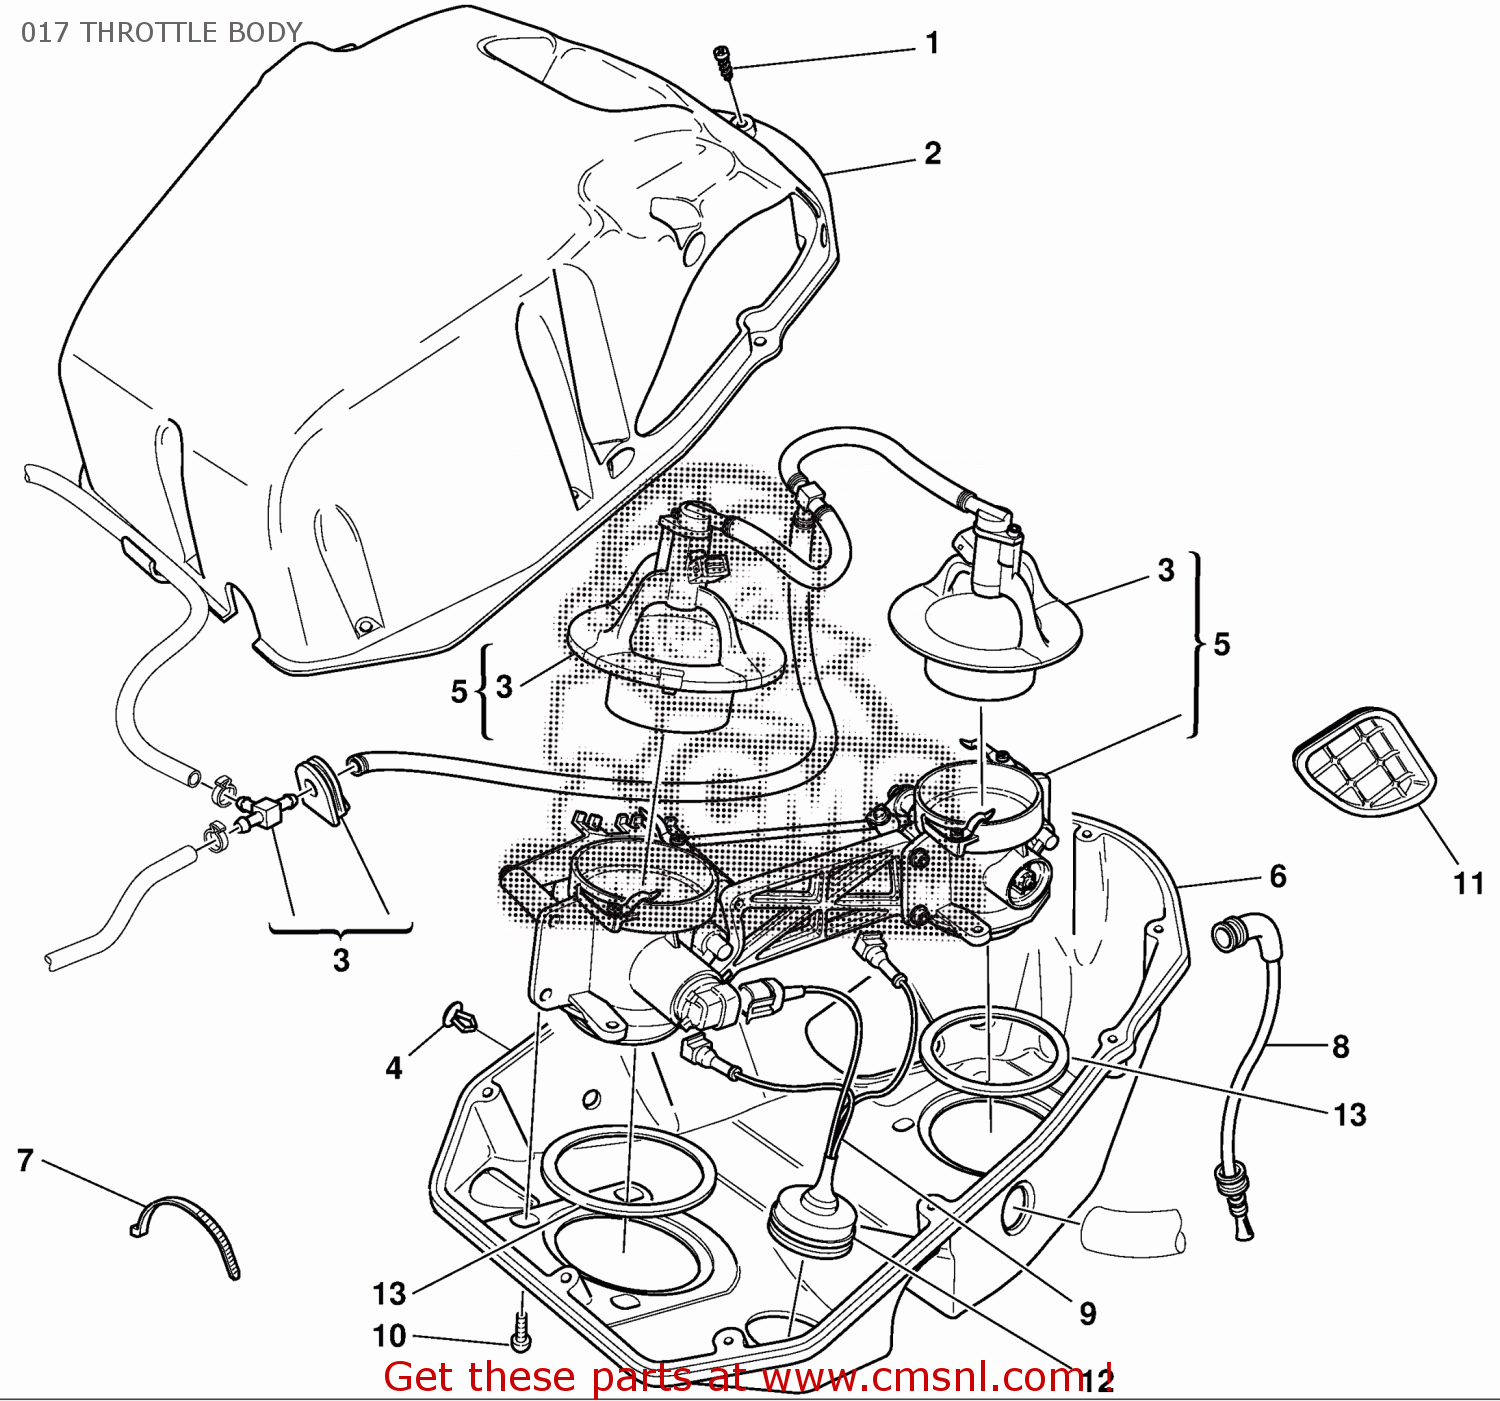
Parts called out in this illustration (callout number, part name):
1	SCREW TAPPING 3.9X25
2	FILTER CASE COVER
3	INJECTOR SET
4	PLUG
5	COMPLETE THROTTLE BODY
6	LOWER FILTER BOX
7	CLAMP
8	HOSE, DRAIN
9	THROTTLE BODY WIRING
10	SCREW TBEI M6X14
11	AIR BOX COWLING
12	RUBBER PAD
13	GASKET
